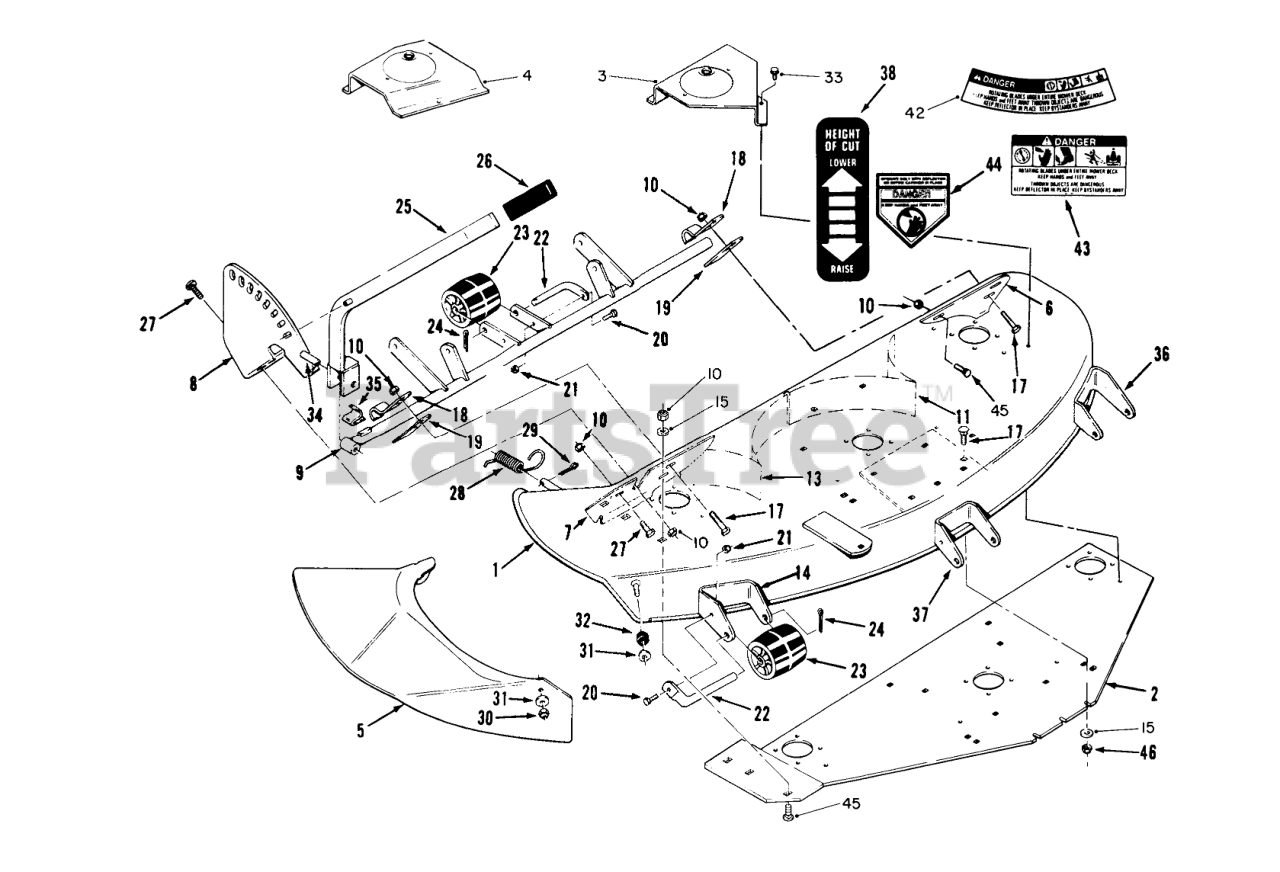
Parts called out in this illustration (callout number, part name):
1	Deck-Mower (Incl. ref. #2,6,7,11,14,36 & 37)
2	Plate-Support
3	Belt Cover LH
4	Belt Cover RH
5	Chute Extension
6	PLATE-WEAR L.H. R
7	Plate-Wear
8	Quadrant
9	Support-Lift
10	NUT-LOCK, NI
11	BAFFLE-DECK LH
13	BAFFLE-DECK RH
14	BRKT-ROLLER R
15	WASHER-FLAT
17	SCREW-CARR
18	Clamp
19	Bar
20	SCREW-HH
21	NUT-LOCK, NI
22	ROLLER-SHAFT
23	Roller
24	PIN-COTTER
25	Lever
27	BOLT-CARR
28	Spring
29	PIN-COTTER
30	Nut
31	Washer
32	BUSHING-PIVOT
33	Bolt
34	SPIROL PIN
35	CLIP-SPRING
36	BRKT-ROLER R
37	BRKT-ROLLER
38	DECAL-HOC
42	DECAL - DANGER
43	DECAL-DANGER, THROWN OBJECT
44	DECAL-DANGER
45	BOLT-CARR
46	NUT-LOCK, NI
